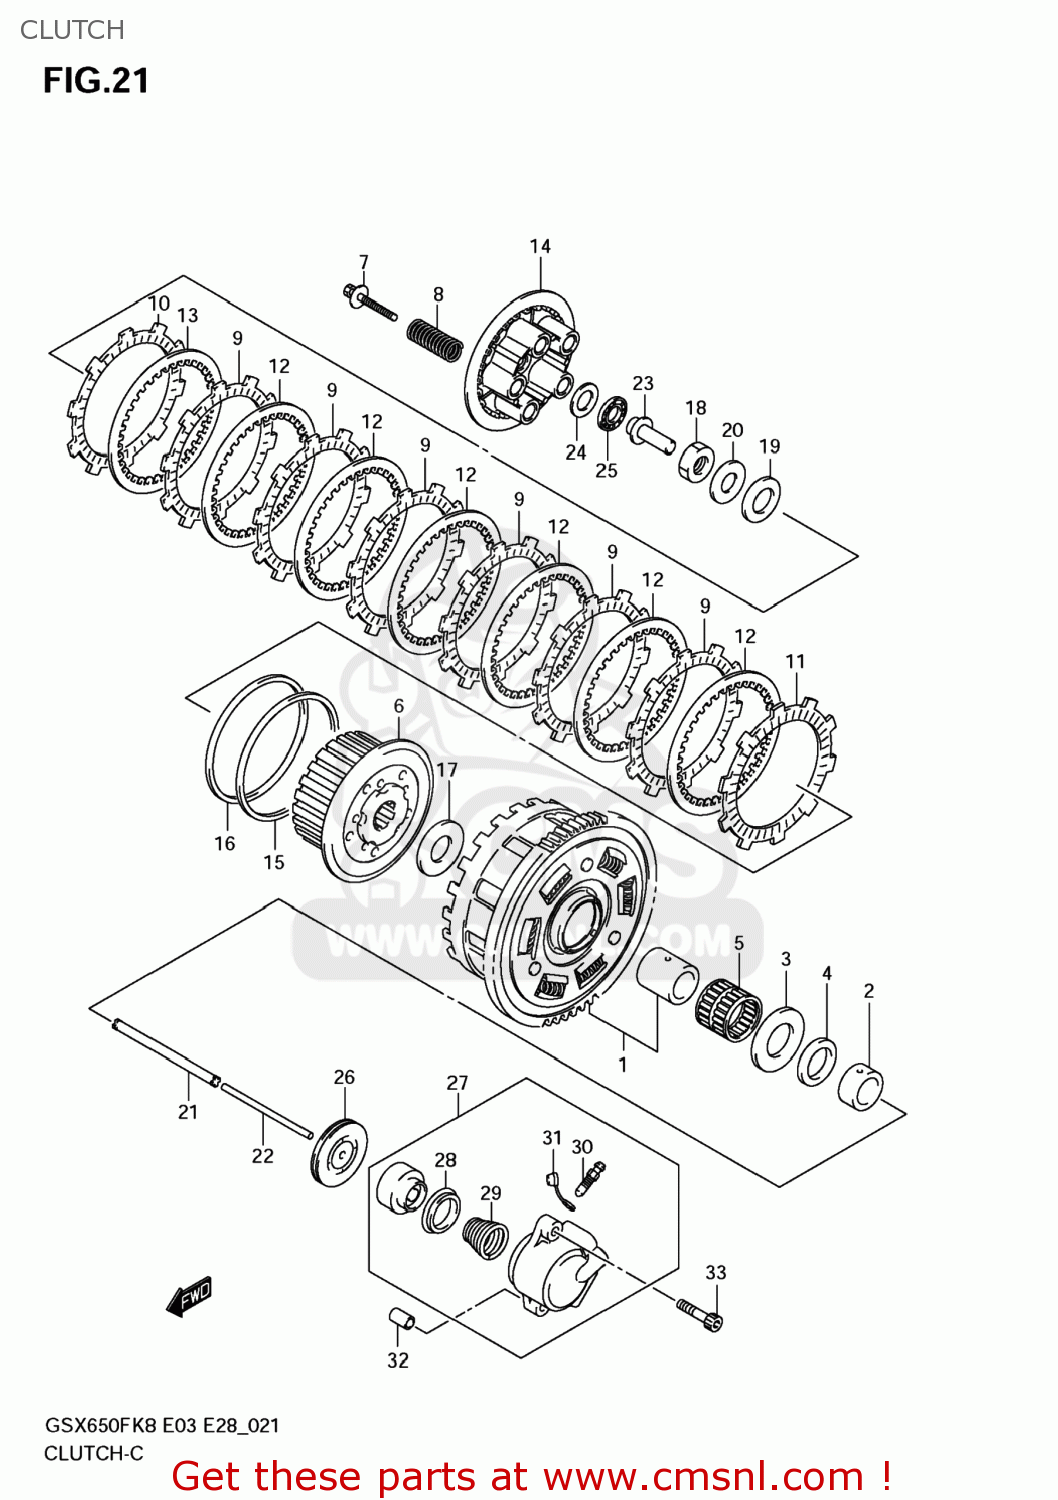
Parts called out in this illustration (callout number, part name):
1	GEAR ASSY, PRIMARY DRIVEN
2	SPACER,OIL PUMP DRIVE SPROCKET
3	WASHER(25X54X2.4)
4	WASHER(25X30X3)
5	BEARING(35X40X26.8)
6	HUB,CLUTCH SLEEVE
7	BOLT,CLUTCH SPRING
8	SPRING,CLUTCH
9	PLATE,CLUTCH DRIVE NO.1 (NAS)
10	PLATE,CLUTCH DRIVE (NAS)
11	PLATE,CLUTCH DRIVE (NAS)
12	PLATE,CLUTCH DRIVEN NO.1 (NAS)
13	PLATE,CLUTCH DRIVEN NO.1 (NAS)
14	DISC,CLUTCH PRESSURE
15	SEAT,CLUTCH PLATE WAVE WASHER
16	WASHER,CLUTCH PLATE WAVE
17	WASHER(25X50X2.5)
18	NUT
19	SHIM(25X38X1)
20	WASHER
21	ROD,CLUTCH
22	ROD,CLUTCH PUSH,L(L:138)
23	PIECE,CLUTCH PUSH
24	WASHER(15.5X28X1)
25	BEARING(15X28X2)
26	SEAL,OIL(6X52X10)
27	CYLINDER,CLUTCH RELEASE
28	CUP,CLUTCH CYLINDER
29	SPRING,CLUTCH CYLINDER
30	BLEEDER
31	CAP,BLEEDER
32	PIN
33	BOLT(6X30)
